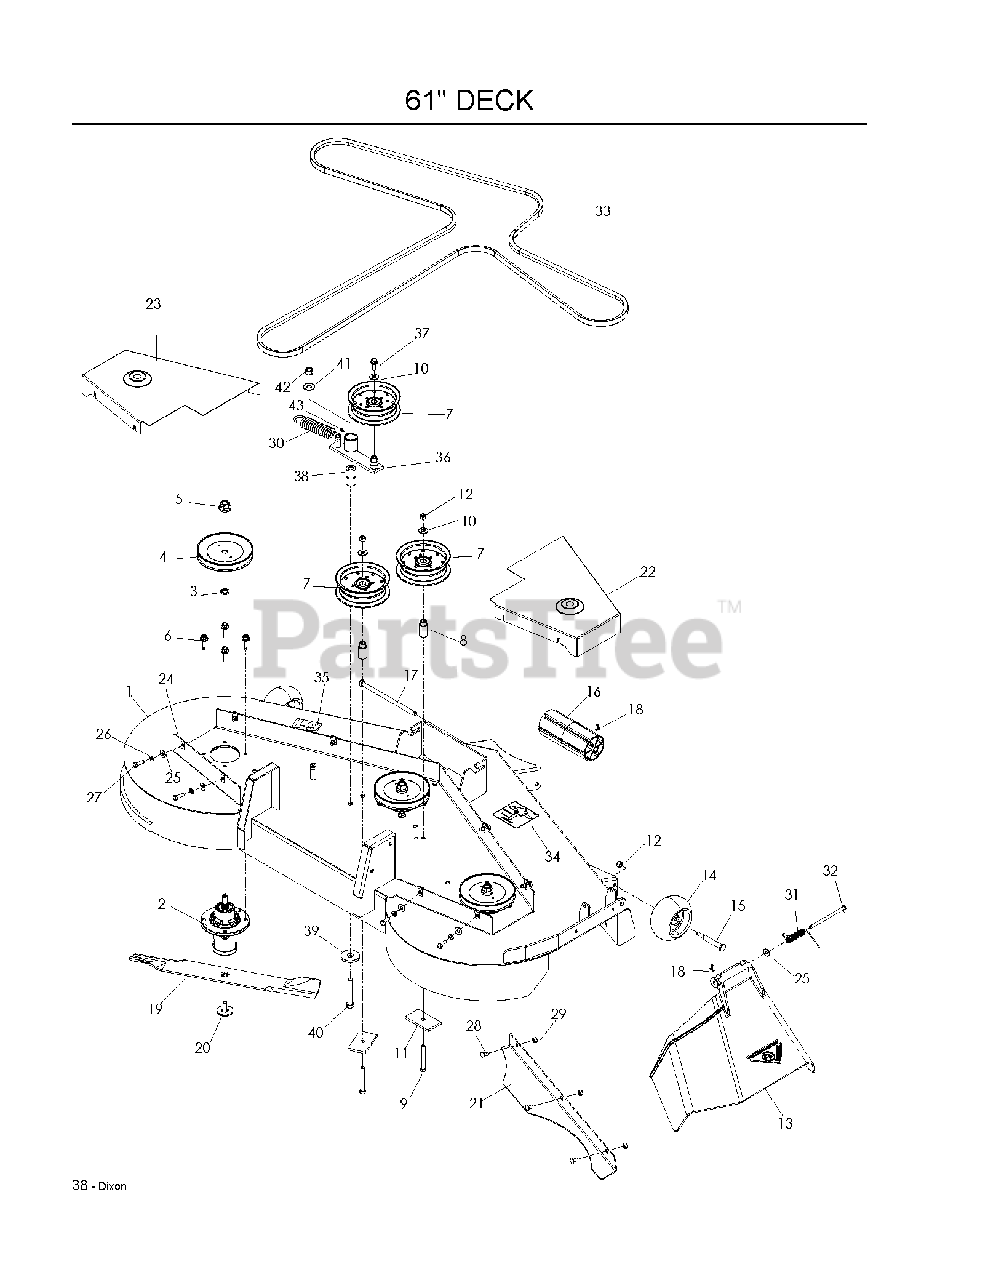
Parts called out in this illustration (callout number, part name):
1	DECK W/DECALS - RAM 61
2	MANDREL.DECK.ASSEMBLY
3	WASHER-SPACER
5	LOCKNUT - 9/16
6	WASHER HEAD SCREW
7	PULLEY, IDLER
8	IDLER BUSHING
9	HCS 3/8C X 3
10	WASHER 3/8 FLAT
11	SUPPORT PLATE
12	NUT 3/8-16 NYLOC
13	DISCHARGE CHUTE 61"
14	GAUGE WHEEL
15	SHOULDER BOLT 1/2X2-5/8 ZD SPE
16	NOSE ROLLER 48"
17	NOSE ROLLER ROD
18	COTTER PIN 1/8 X 3/4
19	BLADE, 21"
20	BLADE BOLT ASSY-7/16" TB REPL
21	CONFINEMENT PLATE 61
22	SHIELD, BELT 61 BLUE RH
24	U-CLIP 5/16-18 NUT RETAINER
25	WASHER 5/16 FLAT
26	WASHER 5/16 LOCK
27	HCS 5/16C X 1
28	CARRIAGE BOLT 5/16C X 5/8"
29	NUT 5/16 NYLOC
31	SPRING - TORSION
32	PIN-CLEVIS 5/16 DIA X 5.19 ZD
33	BELT, DECK - ESTATE
34	DECAL, BELT ROUTING
35	DECAL, 61
36	IDLER ARM
37	HCS 3/8C X 1 SERRATED HEAD
38	PIVOT BUSHING
39	WASHER, SUPPORT
40	HCS 1/2C X 3 1/4
41	WASHER 1/2 FLAT
42	NUT 1/2-13 HEX NYLOC ZD
43	ZERK
